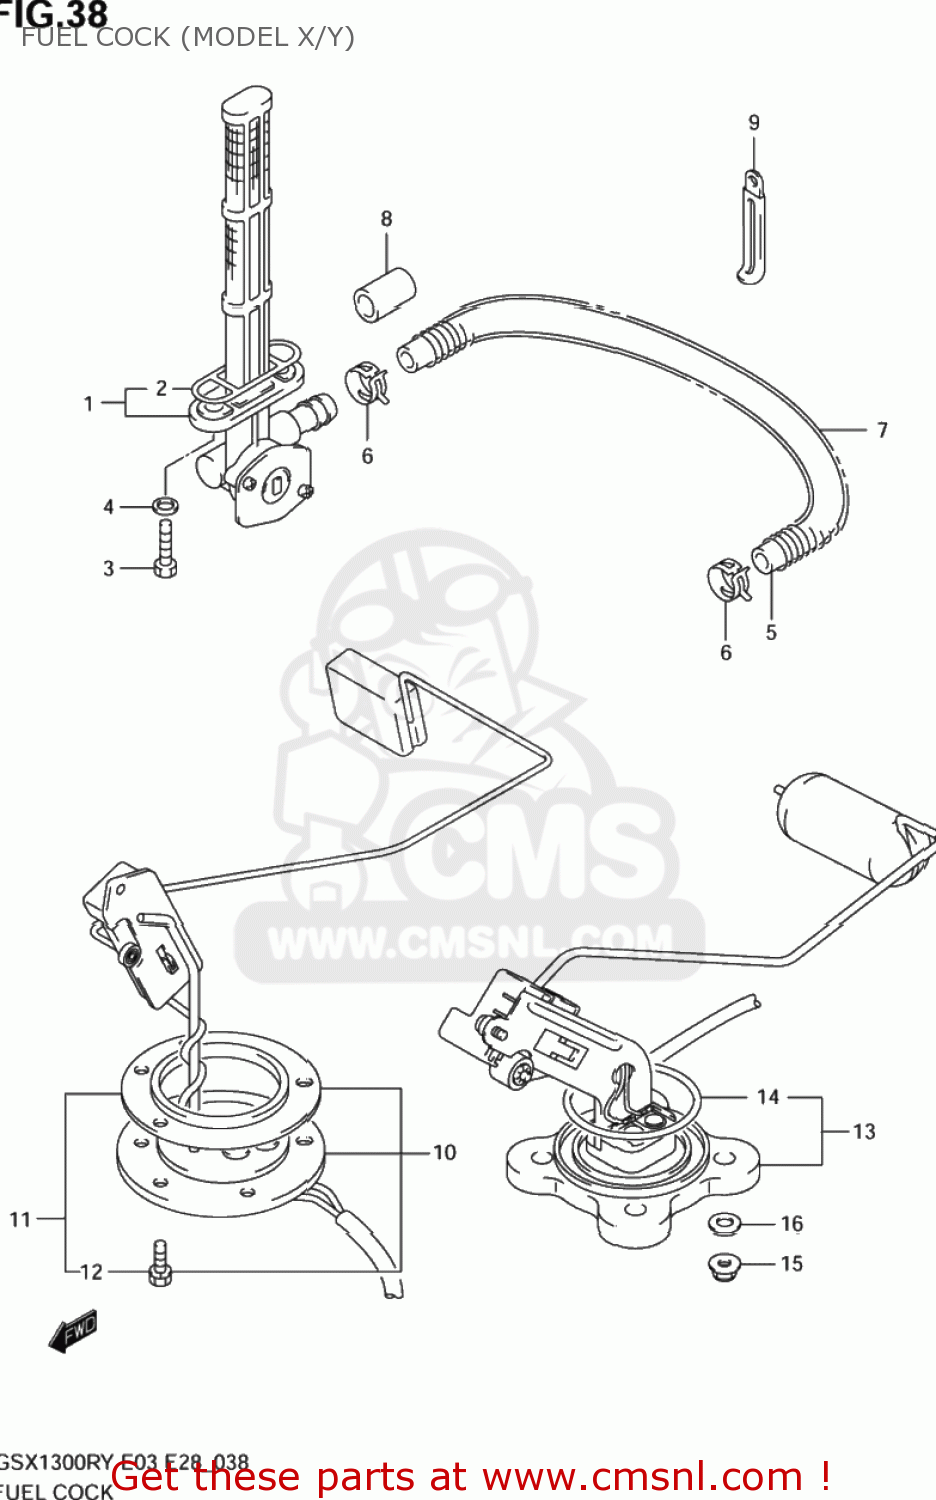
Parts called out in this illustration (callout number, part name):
1	COCK ASSY,FUEL
2	O RING,JOINT
3	BOLT(6X20)
4	GASKET(6.4X11.5X0.8) (NAS)
5	HOSE,FUEL
6	CLIP
7	SPRING,FUEL RETURN HOSE
8	PLUG
9	CLAMP(L:80 T:1.0)
10	FUEL GAUGE SET
11	GASKET SET,FUEL GAUGE (NAS)
12	BOLT,FUEL LEVEL SENDER
13	FUEL GAUGE SET
14	O RING
15	NUT
16	WASHER(6.5X15X1.6)
